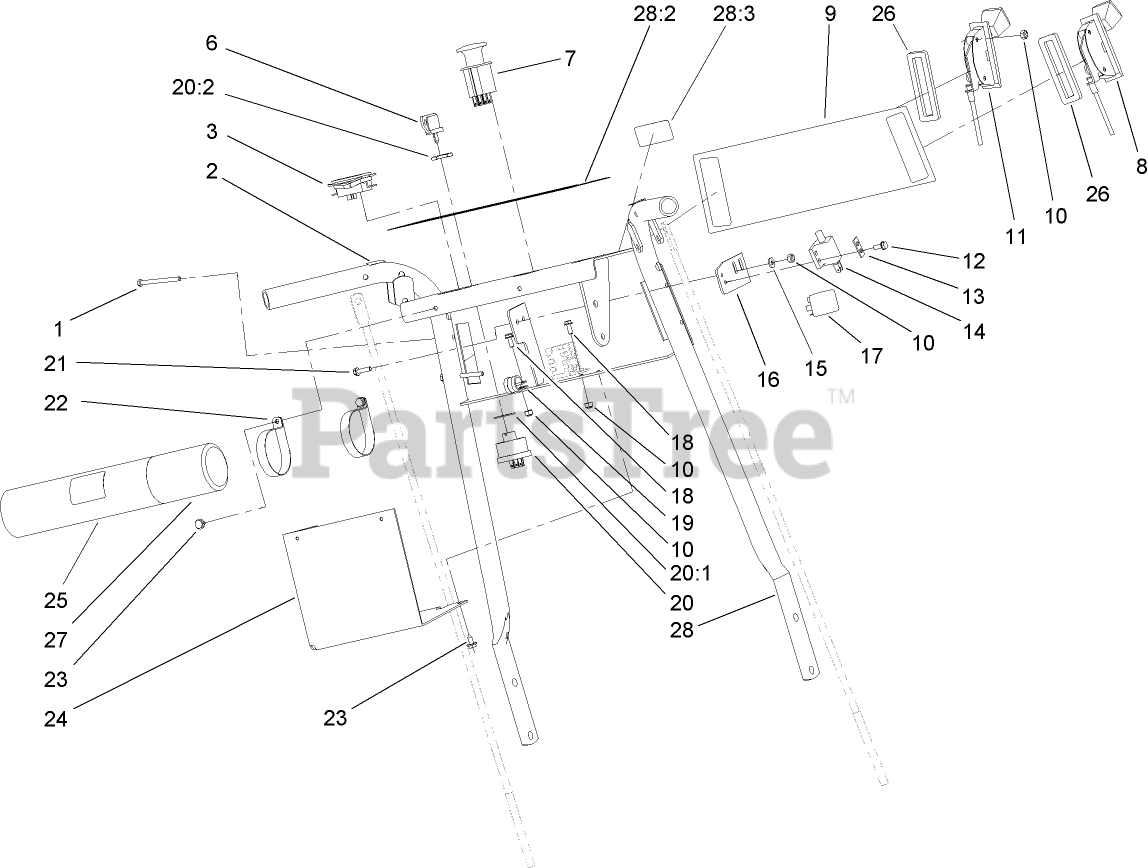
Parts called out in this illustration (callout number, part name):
1	SCREW-SHH
2	DECAL-LOCK, NEUTRAL
3	HOURMETER
6	KEY-IGNITION
7	SWITCH-PTO
8	CONTROL-CHOKE
9	DECAL-CONTROL, THROTTLE
10	NUT-LOCK, NI
11	CONTROL-THROTTLE
12	SCREW-TAPTITE
13	PLATE-SWITCH
14	SWITCH-OPEN, NORMALLY
15	WASHER-FLAT
16	PLATE-MOUNTING, SWITCH
17	RELAY
18	SCREW-HWH
19	CLAMP-R
20	Key Switch ASM
20:1	WASHER-TOOTH, INTERNAL
20:2	NUT-HH
21	SCREW-HWH
22	CLAMP-R
23	SCREW-HWHTF
24	BRACKET-COVER
25	TUBE-MANUAL
26	GASKET-THROTTLE
27	CAP-HOUSING
28	HANDLE ASM
28:2	DECAL-PANEL, CONTROL
28:3	DECAL-PROTECTION, EAR
